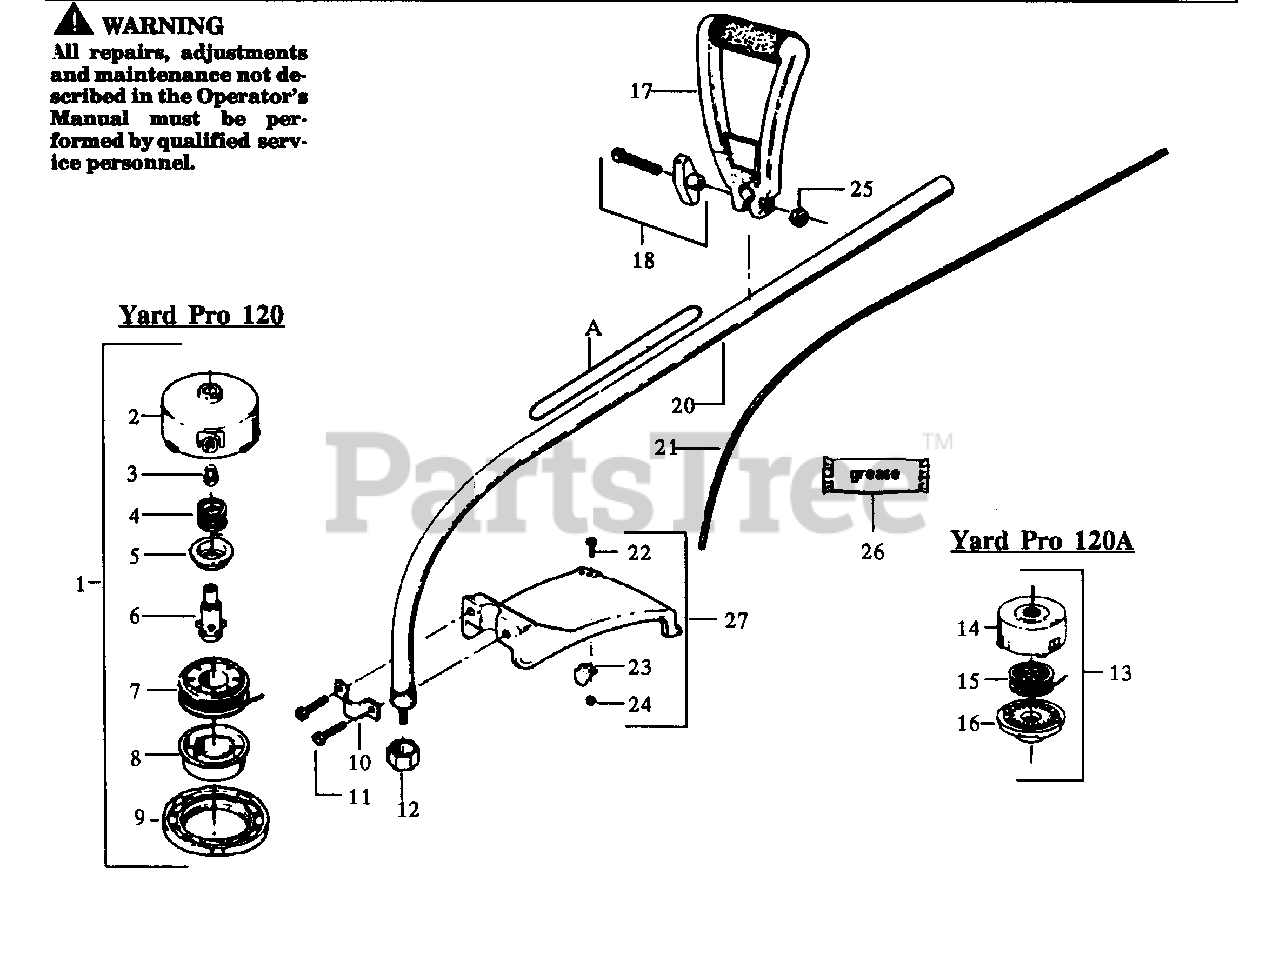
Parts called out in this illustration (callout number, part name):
1	Cutting Head Ass'y. (Inc. #2-9)
2	Hub w/Line Saver
3	Line Saver
4	Spring
5	Adaptor-Spring
6	Drive Gear
7	Spool w/Line
8	Release Button
10	Shield Bracket
11	Screw
12	Model YP120
12	Model YP120A
13	Cutting Head Ass'y. (Inc. #14,15 & 16)
14	Hub w/Line Saver
15	Spool w/Line
17	Assist Handle
18	"T" Handle Ass'y.
20	Model YP120
20	Model YP120A
21	Model YP120
21	Model YP120A
23	Model YP120
23	Model YP120A
24	Nut
26	Shaft Lubrication
27	Shield Kit Ass'y.
A	Safety Label Decal
